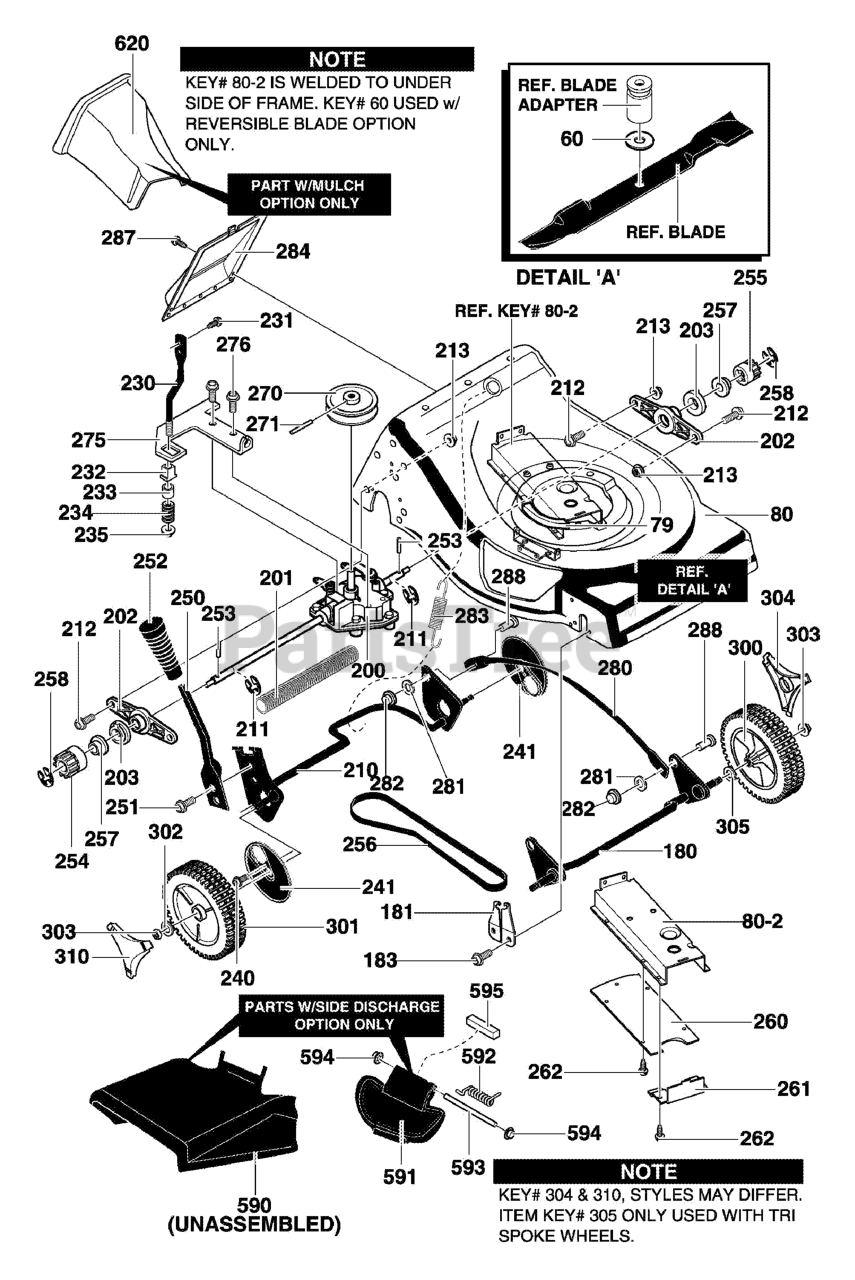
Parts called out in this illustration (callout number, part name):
60	Adapter, Blade
79	Seal, Foam
80	Frame Assembly
80-2	Guard, Belt
180	Assy, Crossbar Front
181	Bushing, Front Housing
183	Screw, 1/4-14x.50
200	Transmission T-Torq
201	Shield, Axle
202	Support, Axle w/Bearing
203	Bearing, Lifter
210	Assy, Crossbar RR
211	Ring, Ret E
212	Screw, 5/16-18 x 0.75
213	Nut, 5/16-18
230	Bearing, Lifter
231	Screw, 1/4-20x.50
232	Bushing, Spring Support
234	Spring, Compression
235	Nut, 5/16-18
240	Screw, 1/4-14x.50
241	Dustcover, 8" Wheel
250	Lever, Spring
251	Screw, 1/4-20x.63
252	Knob, Hgt/Adj
253	Drive Pin
254	Gear, Pinion Right
255	Gear, Pinion Left
256	Belt, V 2L 14.143LG
257	Flatwasher
258	Ring, Ret. E
260	Cover, Lower Belt Guard
261	Cover, Front Belt
262	Screw, 10-16x.50
270	Pulley, 2L T-Torq
271	Pin, Spring
275	Bracket, Transaxle Cable
276	Screw, 1/4-20x.50
280	Link, Lifter
281	Nut, Push On
282	Cap, Push On
283	Spring, Extension
284	Cover, Rear Trans.
287	Screw, 1/4-20x.63
288	Clevis Pin
300	Tire & Rim
301	Wheel, Drive
302	Flatwasher
303	Nut, 3/16-18
305	Washer, Spring
310	Hubcap
590	Deflector, Chute
591	Cover, Mulching
592	Spring, Torsion
593	Rod, Pivot
594	Cap, Push On
595	Seal, Foam
620	Plug, Mulcher Small
